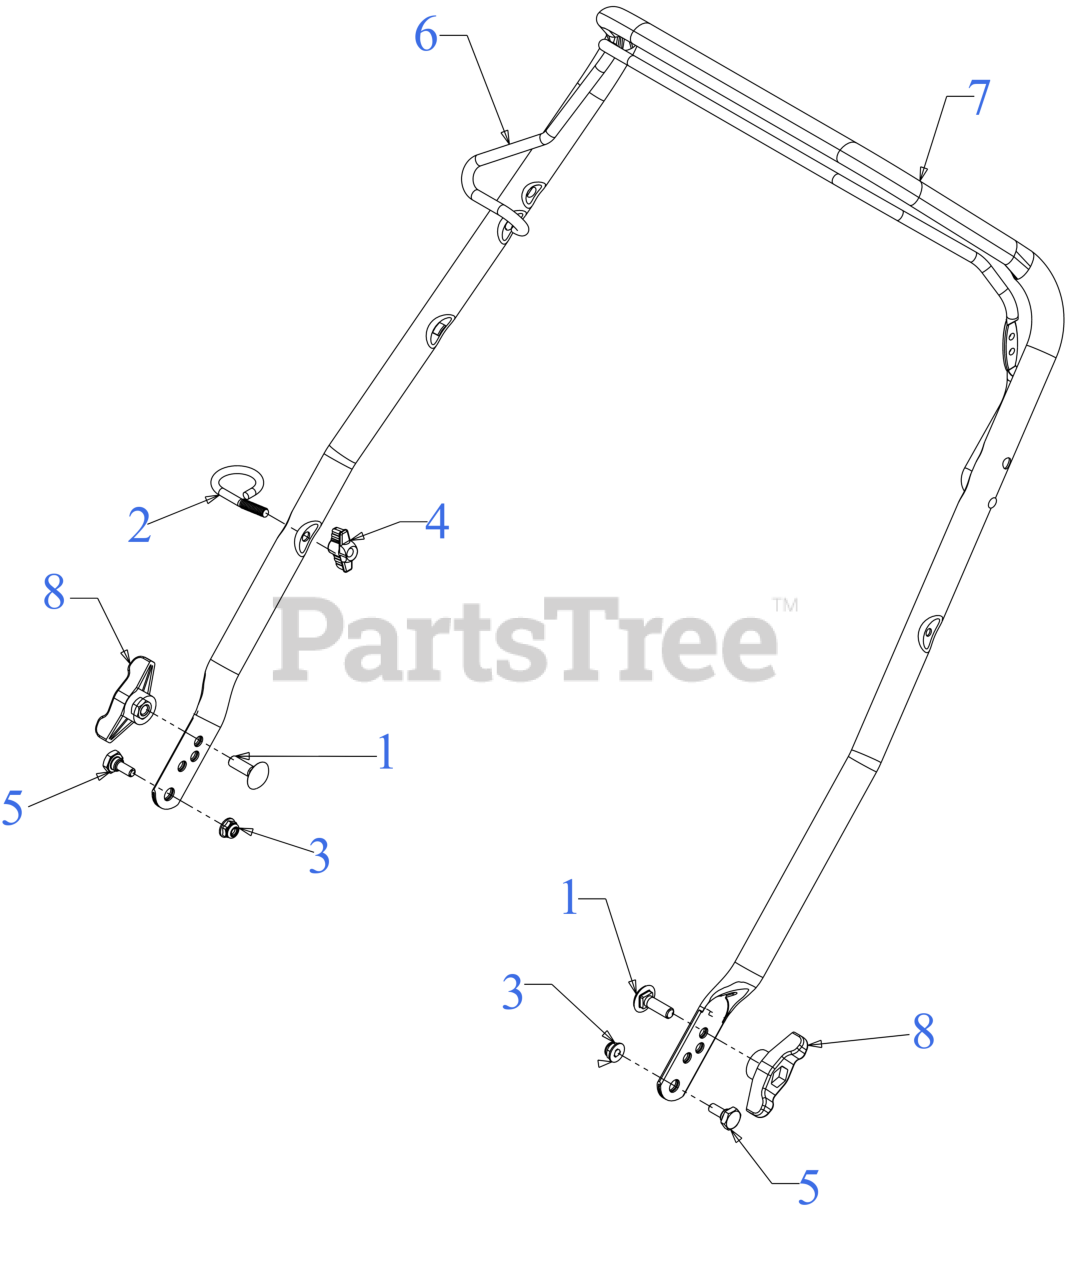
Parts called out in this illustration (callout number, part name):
1	SCREW 5/16-18 x 1.00 GR5
2	EYEBOLT 1/4-20
3	FLANGE LOCK NUT
4	HANDLE KNOB
5	SHOULDER SCREW
7	UPPER HANDLE
8	WING KNOB 5/16-18
